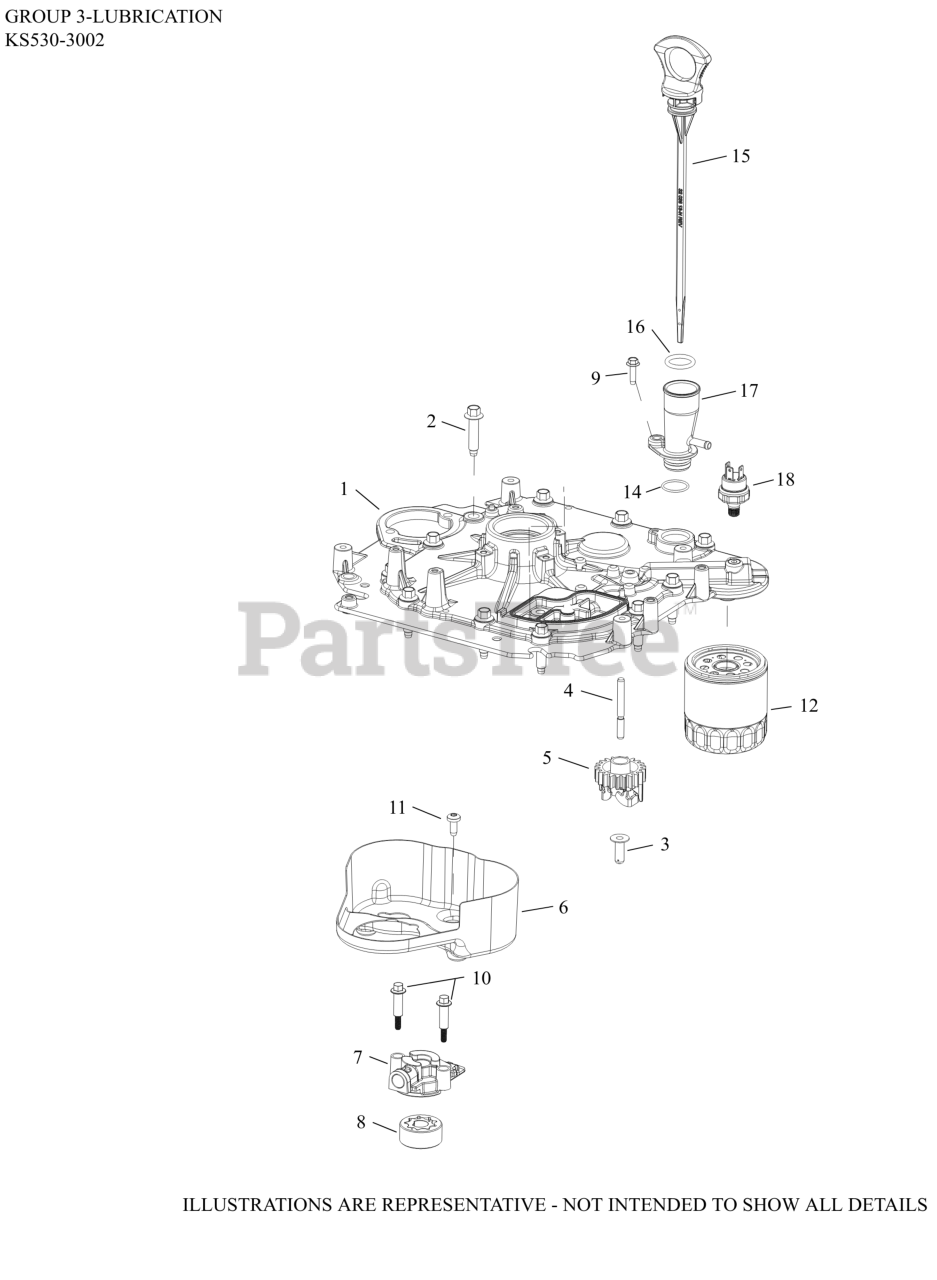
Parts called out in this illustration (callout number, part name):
1	PLATE, CLOSURE ASSY
2	SCREW, HEX FLANGE
3	PIN, GOVERNOR REGULATING
4	SHAFT, GOVERNOR CROSS
5	KIT, GOVERNOR GEAR
6	BAFFLE, OIL
7	HOUSING, OIL PUMP ASSY
8	PUMP ASSY, OIL
9	SCREW, THD FRM-USE 25 086 473-S
10	SCREW, SHOULDER THREAD FORMING
11	SCREW, THREAD FORMING
12	OIL FILTER
15	DIPSTICK, ASSY
17	TUBE, DIPSTICK ASSY
18	SENSOR, OIL PSI 3 TERMINAL
19	SEAL, OIL
